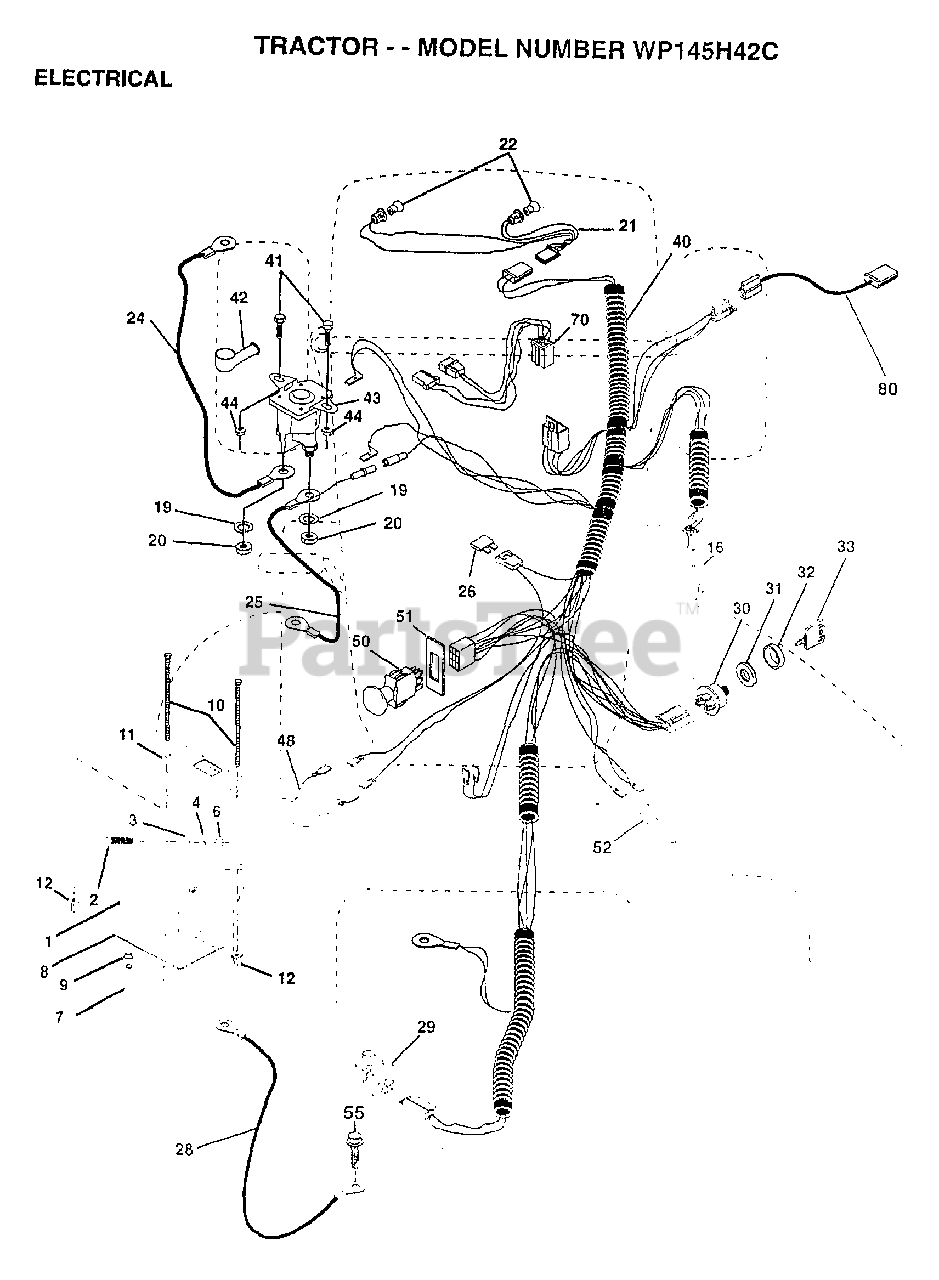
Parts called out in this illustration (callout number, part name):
2	BOLT LT
3	WASHER
4	LOCKWASHER
7	"DRAIN TU T, BATT"
8	"TRAY T, BATTERY"
9	HOSE CLAMP T
11	HOLDDOWN BATTERY
16	SWITCH INTERLOCK
20	NUT
21	HARNESS.ASM.HDLIG
22	HEADLAMP BULB
24	CABLE.BTRY.6GA.RD
25	CABLE.6GA.22W/16W
26	FUSE HYT
28	CABLE.GRND.6GA.21
29	SWITCH SEAT
30	SWITCH IGN 4POS
31	NUT IGNITION
32	COVER KEY SWITCH
33	KEY
40	HARNESS IGNITION
41	BOLT HXHD FIN
44	NUT HXKEP 1/4X20
48	ADAPTER AMMETER
50	PTO SWITCH.BLK
51	RING RETAIN PTO
52	PROTECTION LOOP
55	SCREW LT
70	HARNESS.ENG.DUAL
80	HARNESS.CLUT.EVX.
